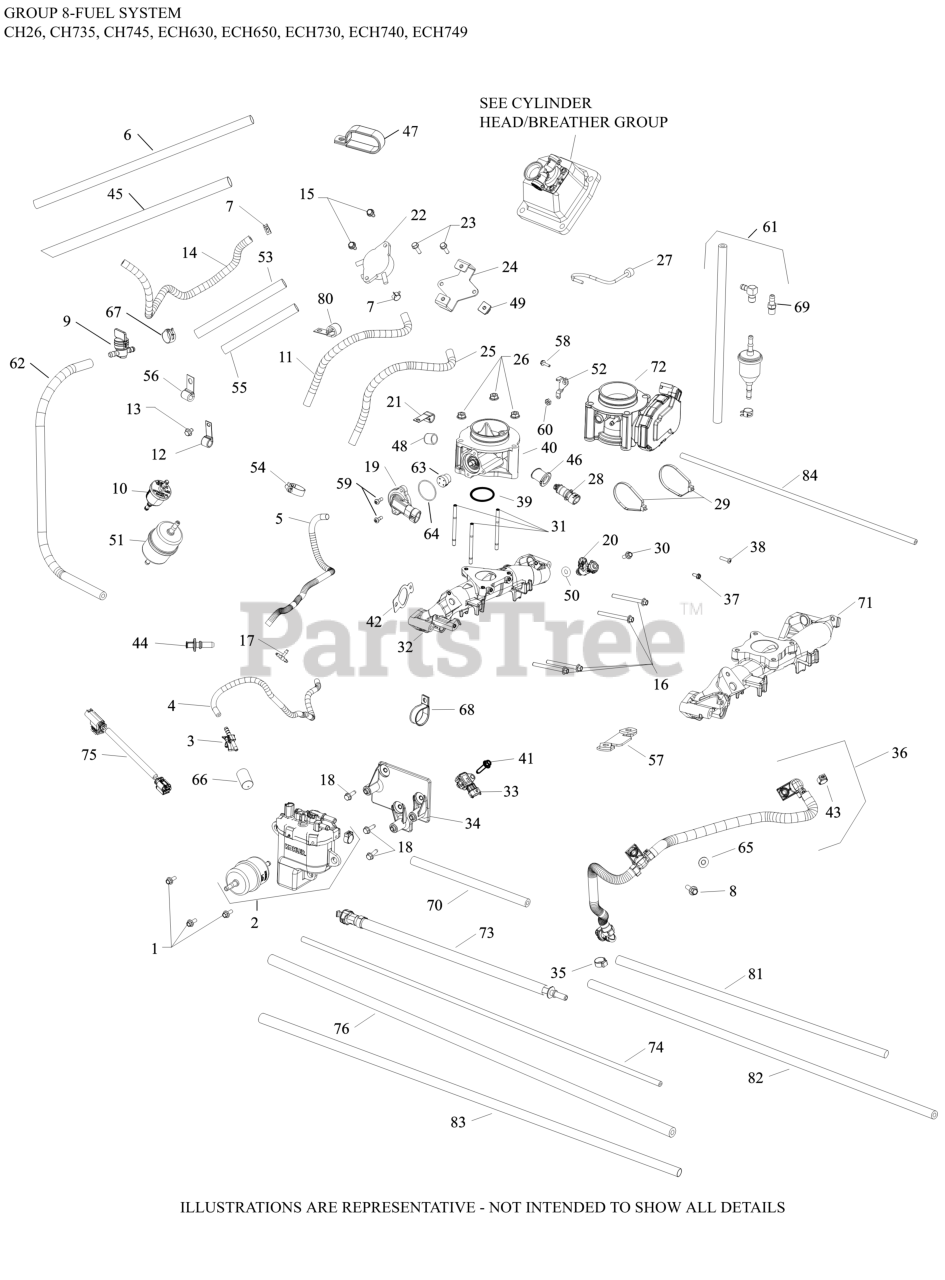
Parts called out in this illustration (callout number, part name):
1	SCREW, FLG M6X1.0X16
2	FUEL PUMP
2	KIT,FP MODULE (ECH/ECV 440,630,940)
4	HOSE, EVAPORATIVE (15.0)
5	SLEEVE, ANTI-ABRASION
7	CLAMP, HOSE (KM)-USE 25 237 31-S
8	SCREW, FLG M6x1.0x20
10	FILTER, FUEL
11	HOSE,LW PERM.FUEL 24.00"-USE 25 111 81-S
16	SCREW, FLG M6X1.0X60
17	TEE CONNECTOR
18	SCREW, THREAD FORMING
19	SENSOR, THROTTLE POSITION
20	INJECTOR, FUEL
21	CLIP, CABLE
31	STUD,M6X1.0X84
32	KIT, MANIFOLD
33	SENSOR, T-MAP
34	BAFFLE, FUEL MODULE
35	CLAMP, HOSE
36	FUEL HOSE ASSEMBLY,ECH680-ECH749
40	BODY, THROTTLE ASM (30)
42	GASKET, INTAKE MANIFOLD-USE 24 041 79-S
43	CLAMP, OETIKER
48	CAP, MASKING
50	KIT, FUEL INJECTOR O-RING
55	SLEEVE, ANTI ABRASION -USE 25 431 12-S
55	SLEEVE, ANTI ABRASION-USE 25 431 12-S
63	MAGNET ASSEMBLY, TPS
64	O-RING, TPS SENSOR
65	CLIP, RETAINER
